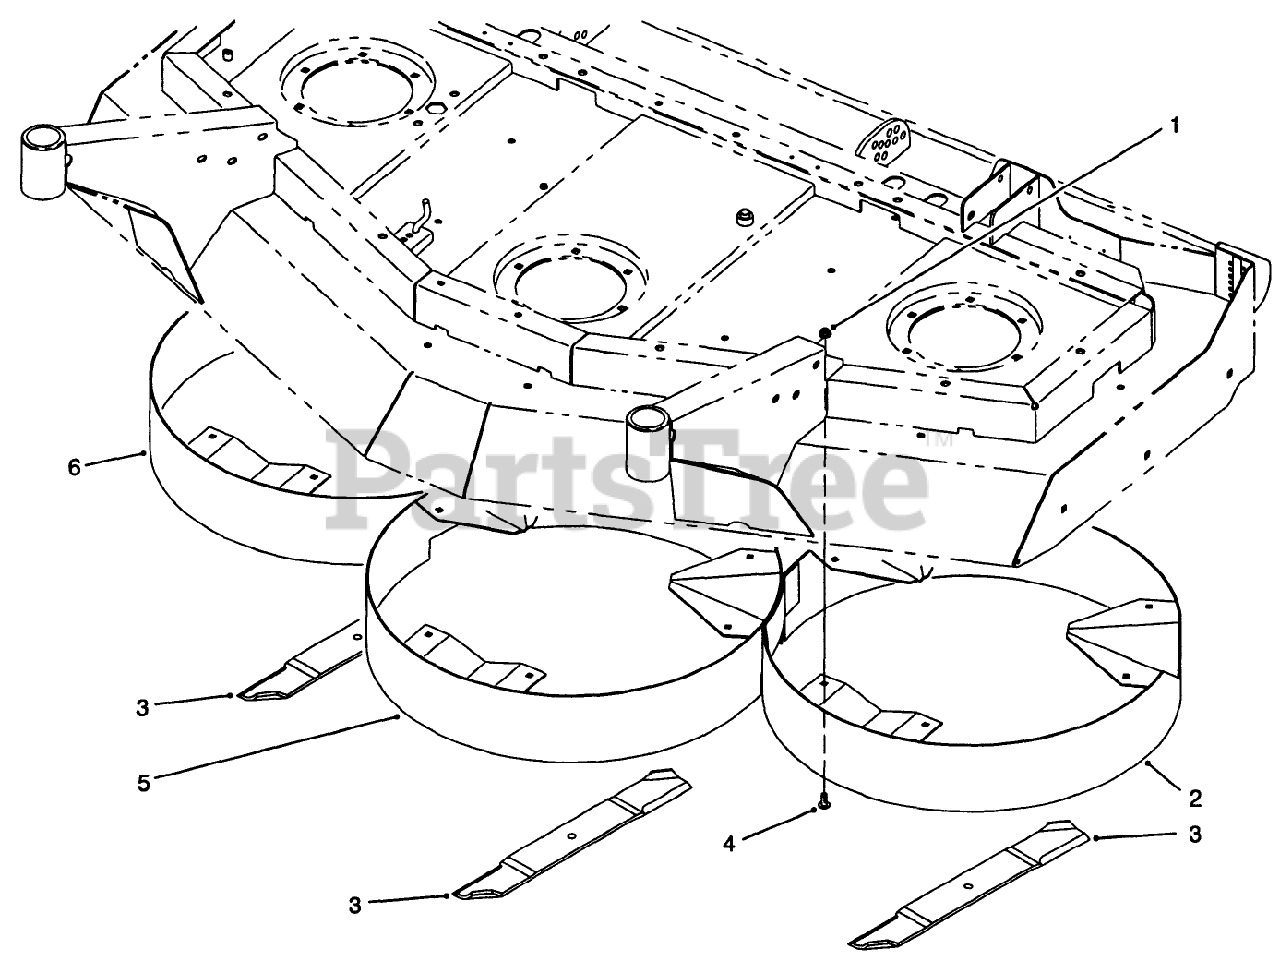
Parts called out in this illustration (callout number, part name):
1	NUT-HF
2	Chamber-LH
3	Blade
4	SCREW-CARR
5	Chamber-Center
6	Chamber-RH
